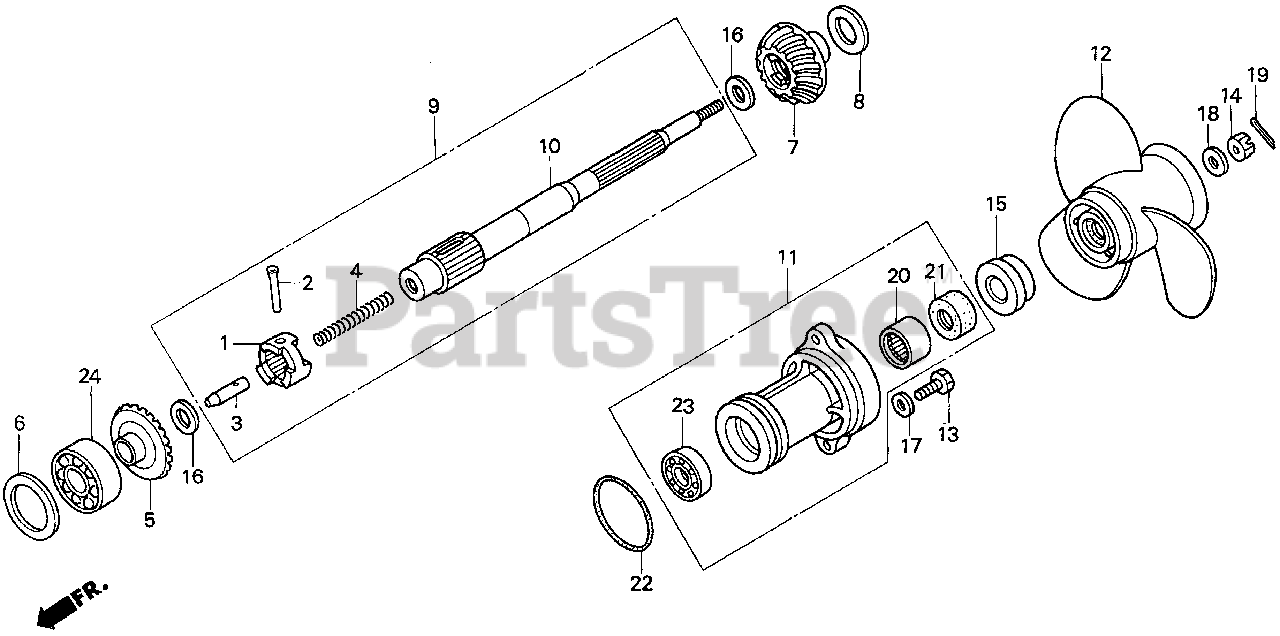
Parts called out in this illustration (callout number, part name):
1	SHIFTER, CLUTCH
2	PIN, SHIFTER (4X35)
3	SLIDER, SHIFT
4	SPRING, SHIFT
5	GEAR, FR. BEVEL (27T)
6	SHIM (40MM) (A)
6	SHIM (40MM) (B)
6	SHIM (40MM) (C)
6	SHIM (40MM) (D)
7	GEAR, RR. BEVEL (27T)
8	SHIM A, GEAR
8	SHIM B, GEAR
9	SHAFT, PROPELLER
10	SHAFT, PROPELLER
11	HOLDER ASSY., PROPELLER SHAFT *NH210MC* (AQUA SILVER METALLIC-C)
11	HOLDER ASSY., PROPELLER SHAFT *NH282MU* (OYSTER SILVER METALLIC-U)
12	PROPELLER, THREE-BLADE (240X220) *NH209* (MARINE WHITE)
12	PROPELLER, THREE-BLADE (9-1/2X8-5/8) *NH283* (STIN GRAY)
13	BOLT, HEX. (6X20)
14	NUT, CASTLE (10MM)
15	WASHER, PROPELLER THRUST
16	WASHER (17MM)
17	WASHER, PLAIN (6MM)
18	WASHER (10MM)
19	PIN, COTTER (3MM)
20	BEARING, NEEDLE (17X23X12)
21	SEAL, WATER (17MM)
22	O-RING (58X3)
23	BEARING, RADIAL BALL (6005)
24	BEARING, RADIAL BALL (6205)
